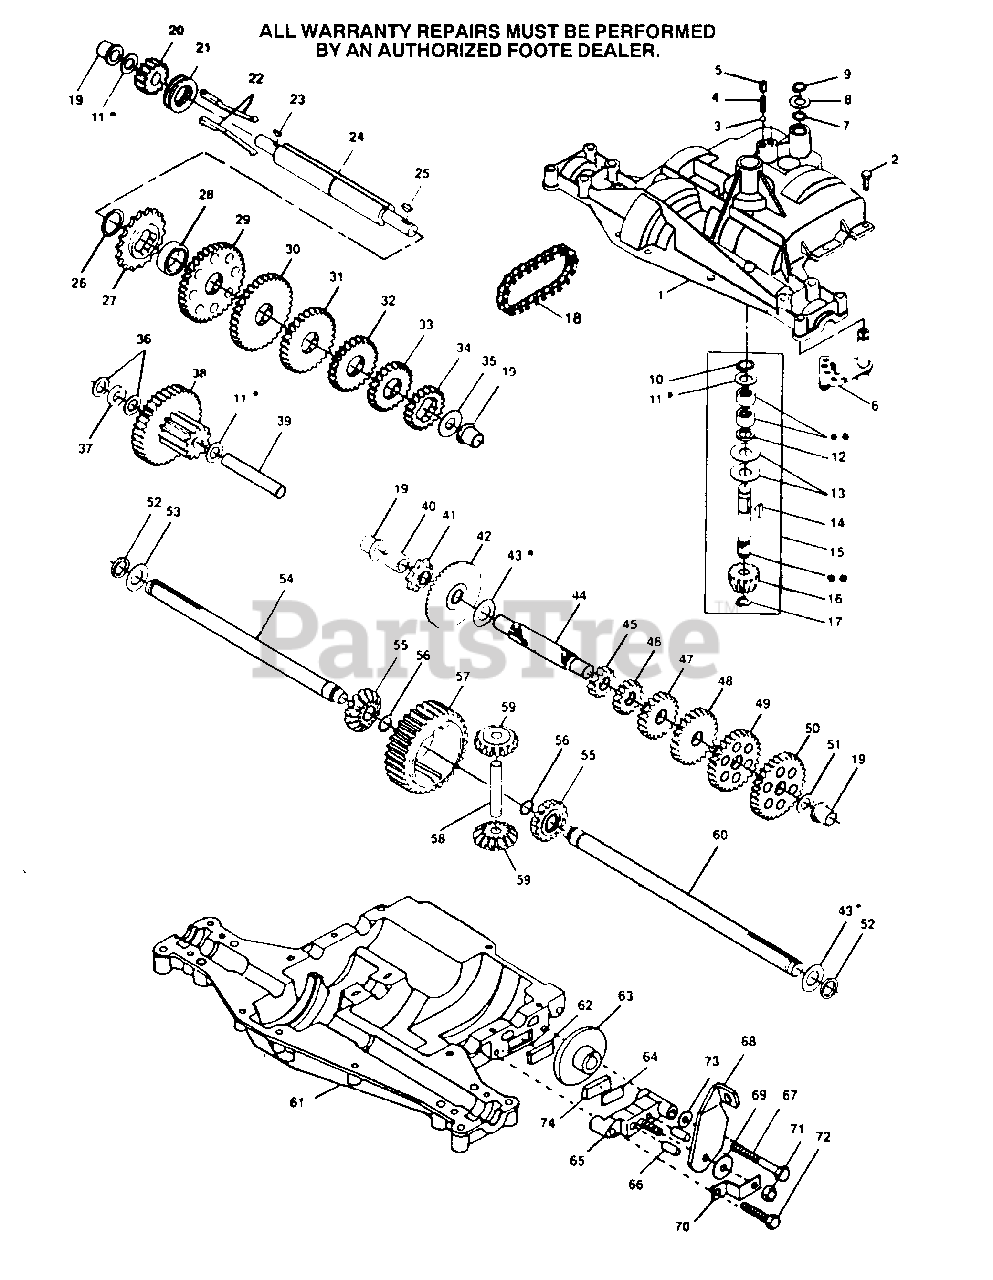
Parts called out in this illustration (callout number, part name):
1	Housing, Upper (Dana part number)
2	Screw, Tapping, Lg. 1/4-20 x .734 (Dana part number)
3	Ball, Detent (Dana part number)
4	Spring, Detent (Dana part number)
5	Screw, Set (Dana part number)
6	Assembly, Shifter (Dana part number)
7	O-Ring (Dana part number)
8	Washer, Plain .505 x .942 x .006 (Dana part number)
8	Washer, Plain .505 x .942 x .010 (Dana part number)
8	Washer, Plain .505 x .942 x .015 (Dana part number)
8	Washer, Plain .505 x .942 x .020 (Dana part number)
8	Washer, Plain .505 x .942 x .026 (Dana part number)
8	Washer, Plain .505 x .942 x .030 (Dana part number)
8	Washer, Plain .505 x .942 x .040 (Dana part number)
9	Ring, Retaining(Dana part number)
10	Ring, Retaining (Dana part number)
11	Washer, Plain .632 x 1.00 x .010 (Dana part number)
11	Washer, Plain .632 x 1.00 x .020 (Dana part number)
11	Plain Washer .632 x 1.00 x .026 (Dana part number)
11	Washer, Plain .632 x 1.00 x .031 (Dana part number)
11	Washer, Plain .632 x 1.00 x .036 (Dana part number)
11	Washer, Plain .632 x 1.00 x .041 (Dana part number)
11	Washer, Plain .632 x 1.00 x .046 (Dana part number)
11	Washer, Plain .632 x 1.00 x .050 (Dana part number)
11	Washer, Plain .632 x 1.00 x .060 (Dana part number)
11	Washer, Plain .632 x 1.00 x .082 (Dana part number)
12	O-Ring (Dana part number)
13	Washer, Plain .632 x 1.38 x .046
14	Key, Woodruff #9
15	Assembly, Kit, Input Shaft (Dana part number)
16	Pinion, Bevel, 14 Teeth (Dana part number)
17	Ring, Retaining (Dana part number)
18	Chain, 24 Pitches (Dana part number)
19	Bearing, Flange (Dana part number)
20	Gear, Spur, 14 Teeth
21	Collar, Clutch (Dana part number)
22	Key, Clutch (Dana part number)
23	Key, Woodruff
24	Shaft, Intermediate (Dana part number)
25	Key, Woodruff #61 (Dana part number)
26	Ring, Retaining (Dana part number)
27	Sprocket, 18 Teeth (Dana part number)
28	Spacer (Dana part number)
29	Gear, Spur, 37 Teeth
30	Gear, Spur, 35 Teeth
31	Gear, Spur, 30 Teeth (Dana part number)
32	Gear, Spur, 25 Teeth
33	Gear, Spur, 22 Teeth (Dana part number)
34	Gear, Spur, 19 Teeth (Dana part number)
35	Washer, Plain .640 x 1.37 x .061 (Dana part number)
36	Plain Washer .632 x 1.00 x .026 (Dana part number)
37	Spacer .630 x 1.00 x .169 (Dana part number)
38	Assembly, Gear, Combination 12 Teeth and 35 Teeth (Dana part number)
39	Shaft, Idler (Dana part number)
40	Spacer .635 x.875 x .755 (Dana part number)
41	Sprocket, 9 Teeth (Dana part number)
42	Gear, Bevel, 42 Teeth (Dana part number)
43	Washer, Plain .758 x 1.12 x .010 (Dana part number)
43	Washer, Plain .758 x 1.12 x .015 (Dana part number)
43	Washer, Plain .758 x 1.12 x .020 (Dana part number)
43	Washer, Plain .758 x 1.12 x .025 (Dana part number)
43	Washer, Plain .758 x 1.25 x .020 (Dana part number)
43	Washer, Plain .758 x 1.25 x .025 (Dana part number)
43	Washer, Plain .758 x 1.25 x .031 (Dana part number)
43	Washer, Plain .758 x 1.25 x .035(Dana part number)
43	Washer, Plain .758 x 1.25 x .040(Dana part number)
43	Washer, Plain .758 x 1.25 x .045(Dana part number)
43	Washer, Plain .758 x 1.25 x .050 (Dana part number)
43	Washer, Plain .758 x 1.25 x .055 (Dana part number)
43	Washer, Plain .758 x 1.25 x .062 (Dana part number)
44	Shaft, Drive (Dana part number)
45	Gear, Spur, 12 Teeth (Dana part number)
46	Gear, Spur, 15 Teeth (Dana part number)
47	Gear, Spur, 20 Teeth (Dana part number)
48	Gear, Spur, 25 Teeth (Dana part number)
49	Gear, Spur, 28 Teeth (Dana part number)
50	Gear, Spur, 31 Teeth (Dana part number)
51	Washer, Plain .632 x 1.00 x .060 (Dana part number)
52	Seal, Felt (Dana part number)
53	Washer, Plain .758 x 1.25 x .062 (Dana part number)
54	Axle, L.H. (Dana part number)
55	Gear, Miter, 15 Teeth
56	Ring, Retaining (Dana part number)
57	Gear, Spur, 32 Teeth (Dana part number)
58	Shaft, Cross (Dana part number)
59	Gear, Miter, 15 Teeth
60	Axle, R.H. (Dana part number)
61	Housing, Lower (Dana part number)
62	Puck, Friction (Dana part number)
63	Disc, Brake(Dana part number)
64	Spacer (Dana part number)
65	Jaw, Brake (Dana part number)
66	Pin, Dowel (Dana part number)
67	Screw, Tapping, Lg. 5/16-18 x 2.25 (Dana part number)
68	Lever, Actuating
69	Washer, Plain .321 x 1.00 x .055
70	Bracket, Anti-Rotation (Dana part number)
71	Locknut 5/16-24 (Dana part number)
72	Screw, Tapping, Lg. 5/16-18 x 1.44 (Dana part number)
73	Washer, Plain .343 x .81 x .059
74	Puck, Friction (Dana part number)
75	Grease (Dana part number)
